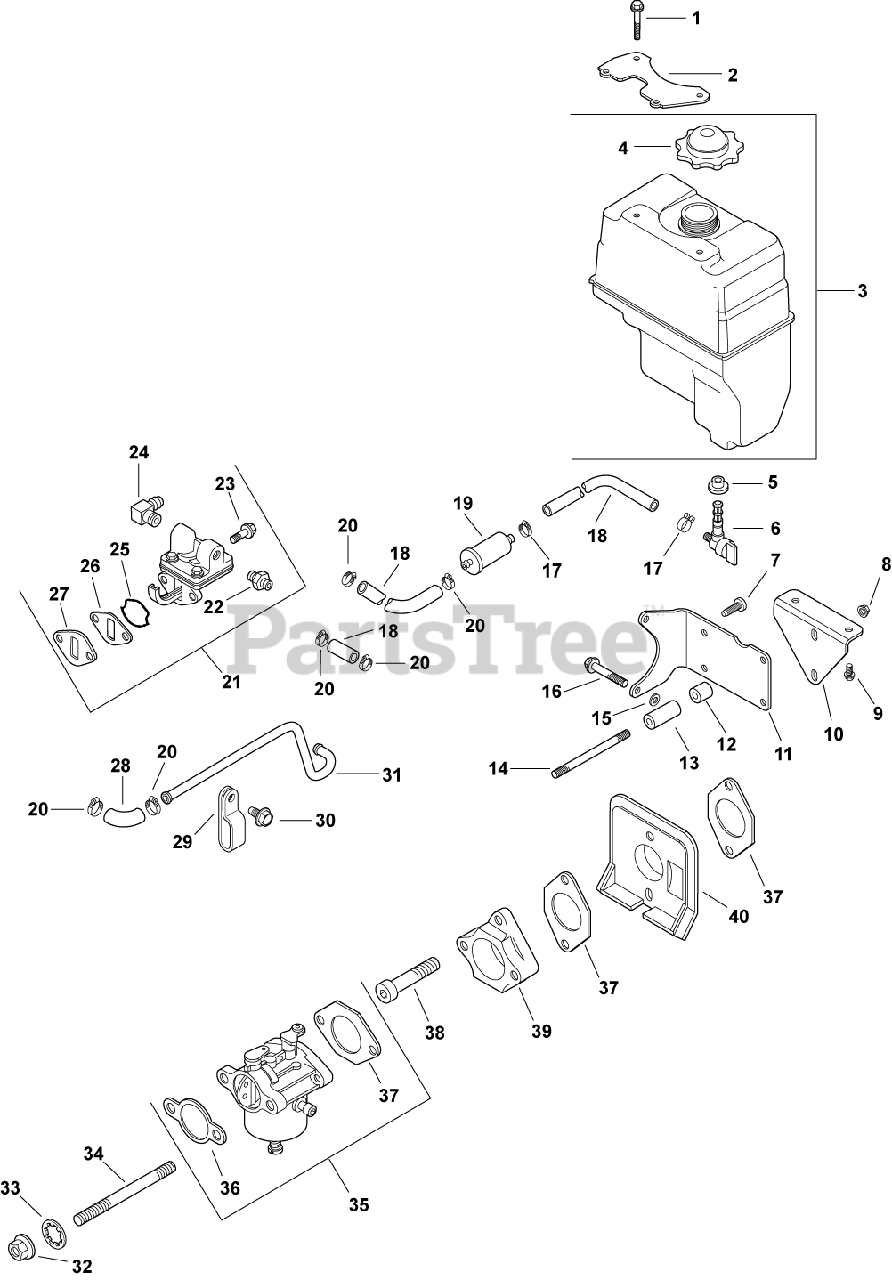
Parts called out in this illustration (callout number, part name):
1	SCREW,FLG THD FRM M6X1.0X25-(#25086395S)
2	BRACKET, FUEL TANK
3	KIT, FUEL TANK
4	CAP, FUEL TANK
5	BUSHING, FUEL TANK
6	VALVE, FUEL SHUT-OFF
7	SCREW, LBD SKT M6x1.0x20-(#25086403S)
8	NUT, FLG M8X1.25
9	SCREW, FLG M6X1.0X12
11	BRACKET, FUEL TANK
14	STUD, M8X1.25X133-USE 25 755 54-S
15	WASHER, FLAT 11/32"
16	SCREW, FLG M8X1.25X50
17	CLAMP, BAND SPRING HOSE-(#2523737S)
18	HOSE,LW PERM.FUEL 24.00"-USE 25 111 81-S
19	FILTER,FUEL 51 MICRON (FUEL PUMP)
20	CLAMP, HOSE (KM)-USE 25 237 31-S
21	KIT, FUEL PUMP
22	KIT, STRAIGHT FITTING
23	SCREW,FLG THD FRM M6X1.0X20-(#25086396S)
24	CONNECTOR, 90 DEG. HOSE
25	O-RING, FUEL PUMP
26	SPACER, FUEL PUMP
27	GASKET, FUEL PUMP
28	HOSE, FUEL LOW-PERMEATION
30	SCREW, FLG THD FRM M5X.8X10
31	LINE, FUEL - DISCONTINUED
32	NUT, FLG M6X1.0
33	WASHER, INT TOOTH LOCK 1/4"
34	STUD,M6X1.0X116
35	KIT, CARBURETOR
36	GASKET, AIR CLEANER BASE
37	GASKET, CARBURETOR
38	SCREW, SKT CAP M6X1.0X35
39	ADAPTER, CARBURETOR
40	DEFLECTOR, HEAT
